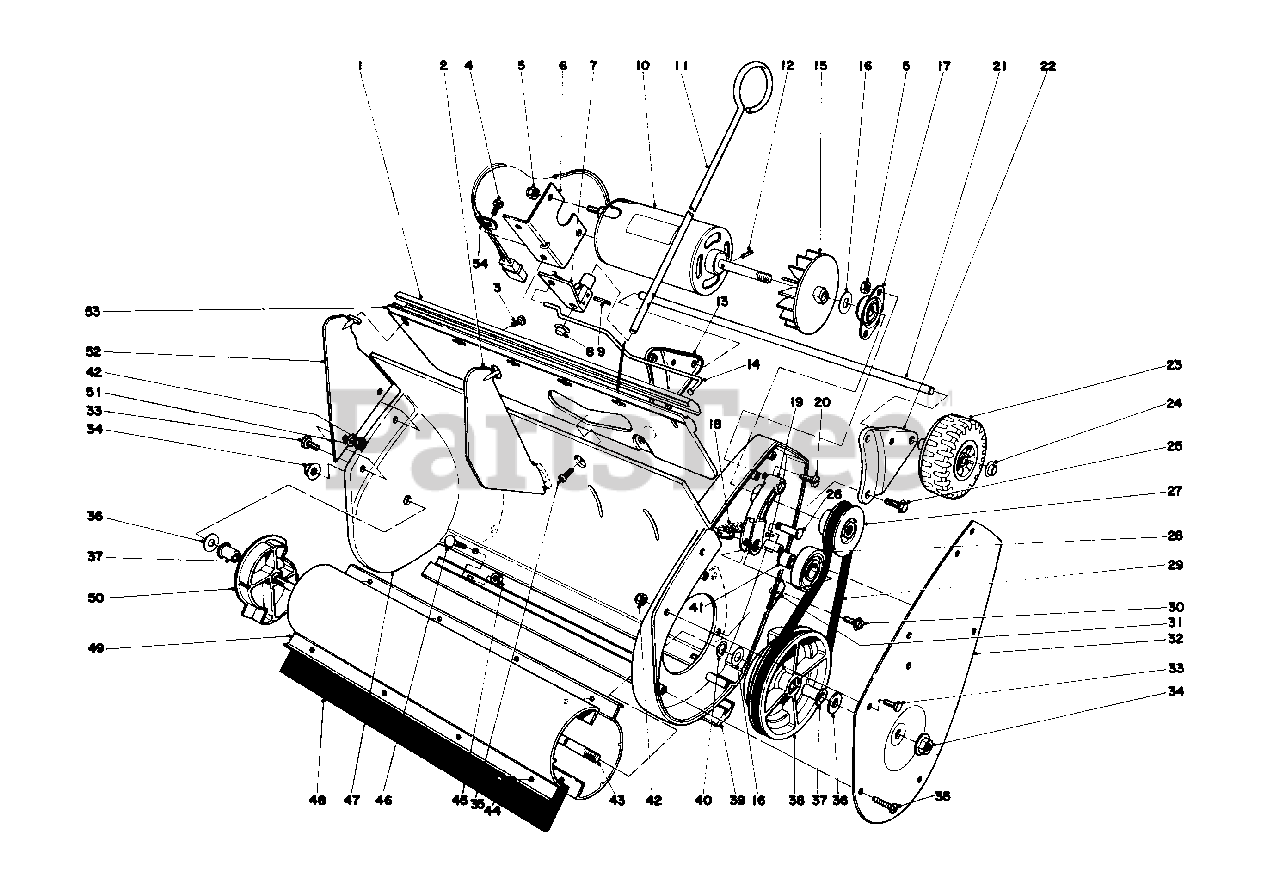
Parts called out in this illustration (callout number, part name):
1	Moulding
2	Vane (Inner)
6	Bracket Mounting
7	Bracket Vane adjustment
11	Rod Vane adjustment
13	Wheel Bracket R.H.
14	Linkage Vane adjustment
16	Thrust Washer
17	Side Flange Bearing
18	Idler Spring
19	Idler Arm
21	Axle Shaft
22	Wheel Bracket L.H.
24	Push Nut
26	Pin Idler
27	Drive Pulley
28	Ball Bearing
29	Drive Belt
31	Nut (Tinnerman)
32	Cover-Belt Case
35	Screw
36	Thrust Washer
37	Rotor-Bushing
38	Pulley-Driver
39	Scraper
40	Retaining Ring
43	Shaft-Rotor
44	Screw Thread Forming
46	Carriage Bolt
48	Blade-Rotor
50	End Cap Rotor
51	Washer
52	Vane-Outer
53	Vane Mount
